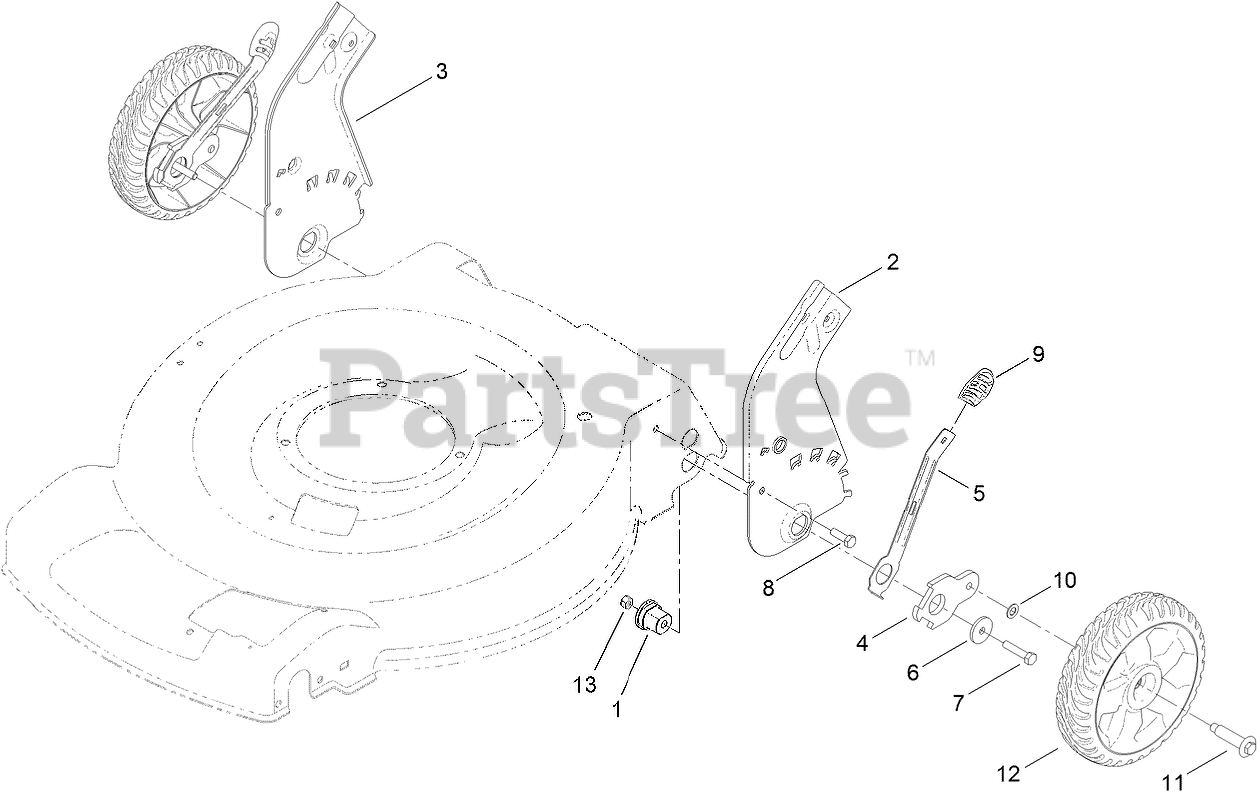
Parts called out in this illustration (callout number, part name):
1	BUSHING-MOUNT, HOC
2	PLATE-HOC, REAR (LH)
3	PLATE-HOC, REAR (RH)
4	ARM-PIVOT, REAR
5	ARM-SPRING, REAR
6	Washer-Flat
7	SCREW-HH
8	SCREW-HH
9	Knob-Lever, HOC
10	WASHER
11	BOLT-SHOULDER
12	8 INCH WHEEL ASM
13	NUT-LOCK, NI
